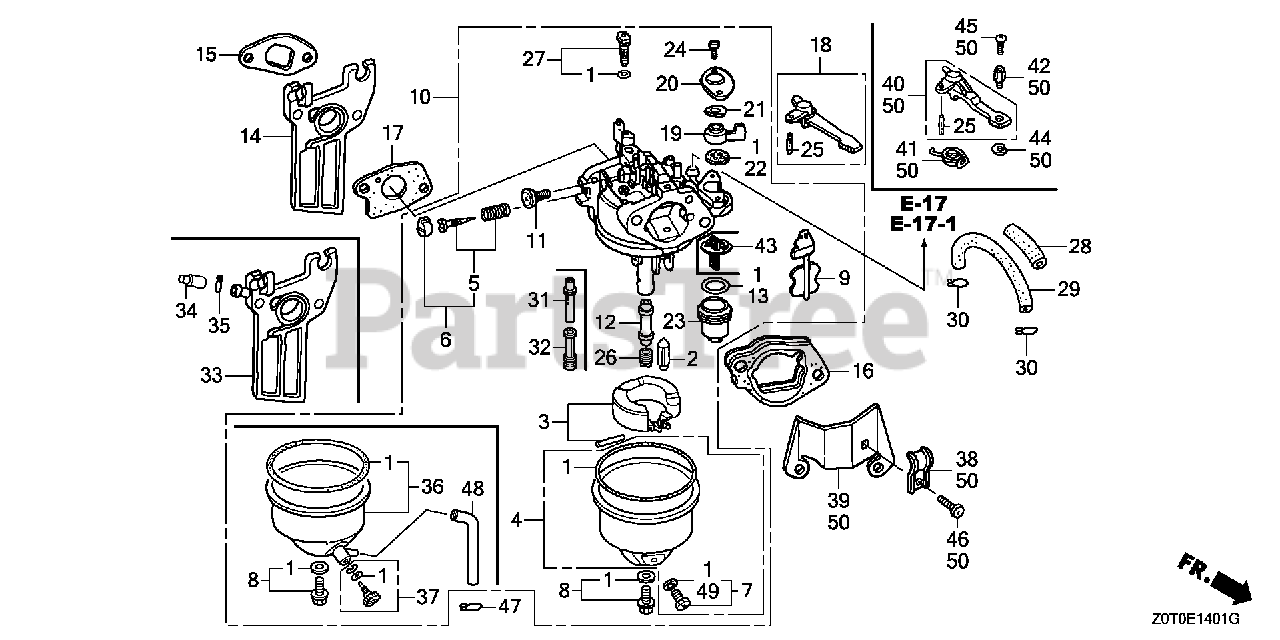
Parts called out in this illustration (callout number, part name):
1	GASKET SET
2	VALVE SET, FLOAT (CARBURETOR NO.) (SEAT NOT INCLUDED)
3	FLOAT SET
4	CHAMBER SET, FLOAT
6	SCREW SET (Honda Code 4219879). (CARBURETOR NO.)
7	SCREW SET, DRAIN
8	SCREW SET (CARBURETOR NO.)
9	CHOKE SET (CARBURETOR NO.)
10	CARBURETOR ASSY. (BEA4Y A)
11	SCREW, THROTTLE STOP
12	NOZZLE, MAIN
13	GASKET, FUEL STRAINER CUP
14	INSULATOR, CARBURETOR
15	GASKET, INSULATOR
16	SPACER, CARBURETOR
17	GASKET, CARBURETOR
18	LEVER, CHOKE (STD)
19	LEVER, VALVE
20	PLATE, LEVER SETTING (CARBURETOR NO.)
21	SPRING, PETCOCK LEVER (CARBURETOR NO.)
22	GASKET, VALVE
23	CUP, FUEL STRAINER
24	SCREW, PAN (3X6)
25	PIN, SPRING (2X12)
26	JET, MAIN (#68)
26	JET, MAIN (#70)
26	JET, MAIN (#72) (CARBURETOR NO.)
26	JET, MAIN (#75) (CARBURETOR NO.)
27	JET SET, PILOT (#35)
43	FILTER, CUP (CARBURETOR NO.)
49	WASHER, PLAIN (6.2X10.7 DRAIN) (CARBURETOR NO.)
